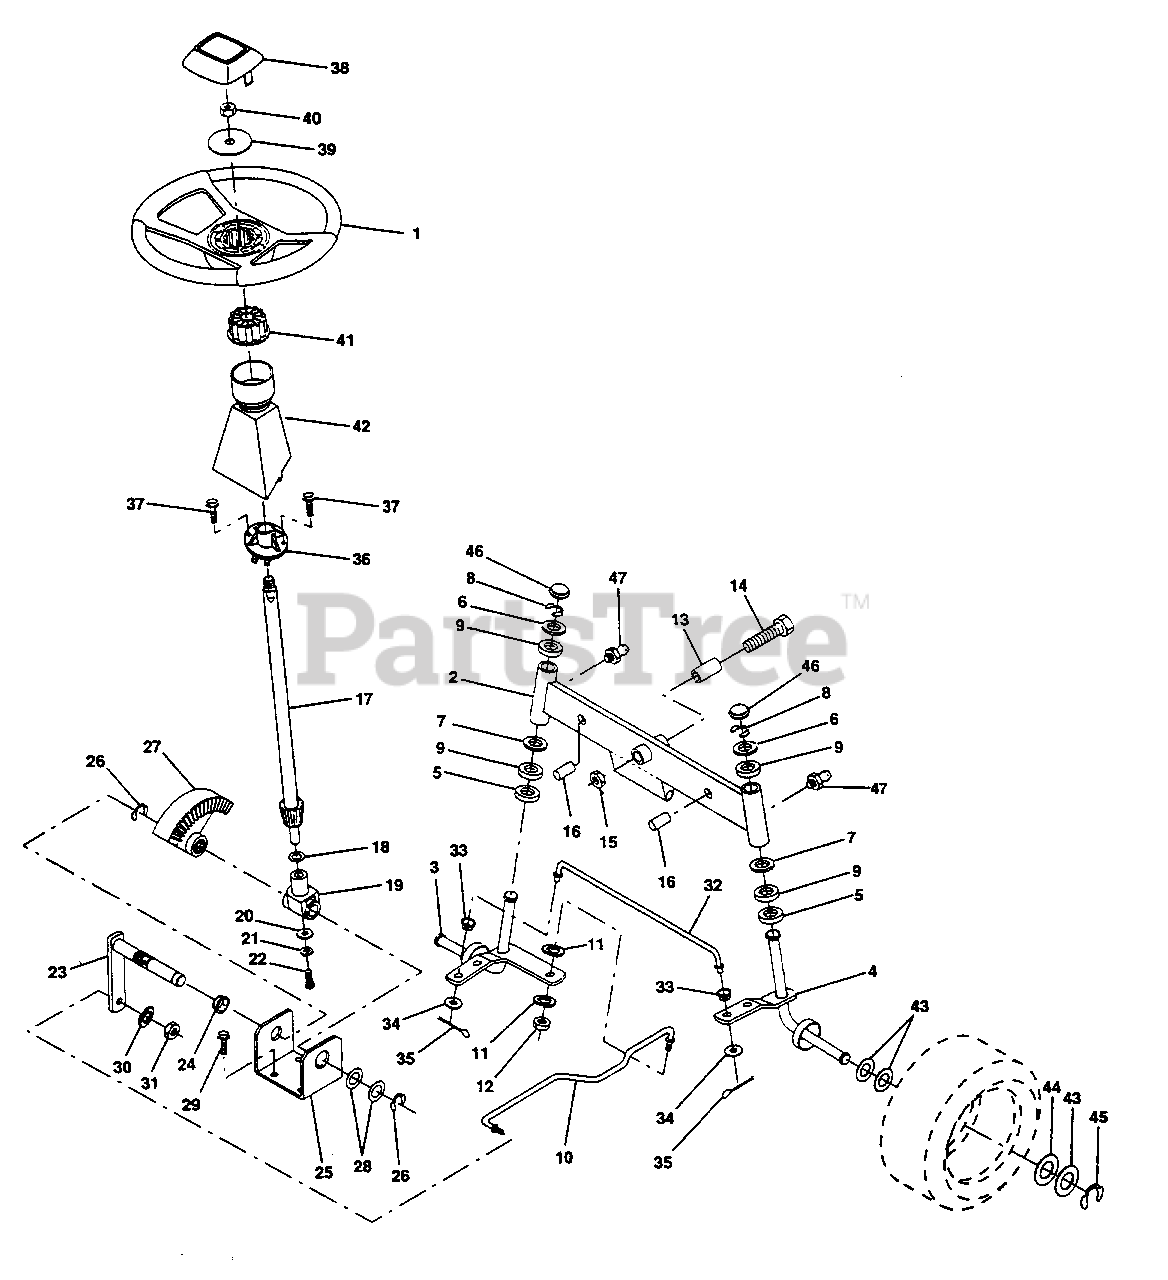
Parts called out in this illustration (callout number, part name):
1	Wheel Steering Auto Blk
2	Axle Asm Fr LT W/gzks 38/42
3	Spindle Asm LH
4	Spindle Asm RH
5	Bearing Race Thrust Harden
6	Washer 25/32 X 1-5/8 X 16 Ga
7	Washer 27/32 X 1-1/4 X 16 Ga
8	Ring Klip #t5304-75
9	Bearing Col Strg Blk
10	Link Drag Sol Ball Jt 20 064
11	Washer Lock Hvy HlcI Spr 3/8
12	Nut Fin Hex 3/8-24 Unf
13	Spacer Bearing Axle Front
14	Bolt Hex 5/8-11 Unc X 3-1/2
15	Nut Lock Flange 5/8-11 Unc
16	Pin Axle 5/8 X 1 55/1 54 Lg
17	Shaft Asm Strg 5/8 X 15 19 LT
18	Washer Thrust 515x 750x 033
19	Support Shaft
20	Washer Shim 1/4 X 5/8 X 062
21	Washer Lock Hvy Helical 1/4
22	Screw Hex Socket 1/4-20 X 5/8
23	Shaft Asm Pittman
24	Nyliner Snap In
25	Bracket Steering
26	Ring Klip #t5304-75
28	Bearing Race Thrust Harden
29	Screw Thdrol 3/8-16x3/4 Ty-tt
30	Washer Lock Hvy HlcI Spr 3/8
31	Nut Fin Hex 3/8-24 Unf
32	Rod Tie Wire Form 19 75 Mech
33	Bushing Link Drag Blk LR
34	Washer 13/32 X 7/8 X 16 Ga
35	Pin Cotter 1/8 X 3/4 Cad
36	Bushing Strg 5/8 Id Dash
37	Screw Slftp #10-16 X 1/2 Ty-b
38	Insert Cap Strg Wheel Blk
39	Washer 13/32 X 2-3/8 X 8 Ga
40	Nut Lock Center 3/8-24unf
41	Adaptor Wheel Strg 640/ 635id
42	Boot Shaft Steering Blk
43	Washer 25/32 X 1 1/4 X 16 Ga
44	Washer 25/32 X 1-5/8 X 16 Ga
45	Ring Klip #t5304-75
46	Cap Spindle Fr Top Blk
47	Fitting Grease
